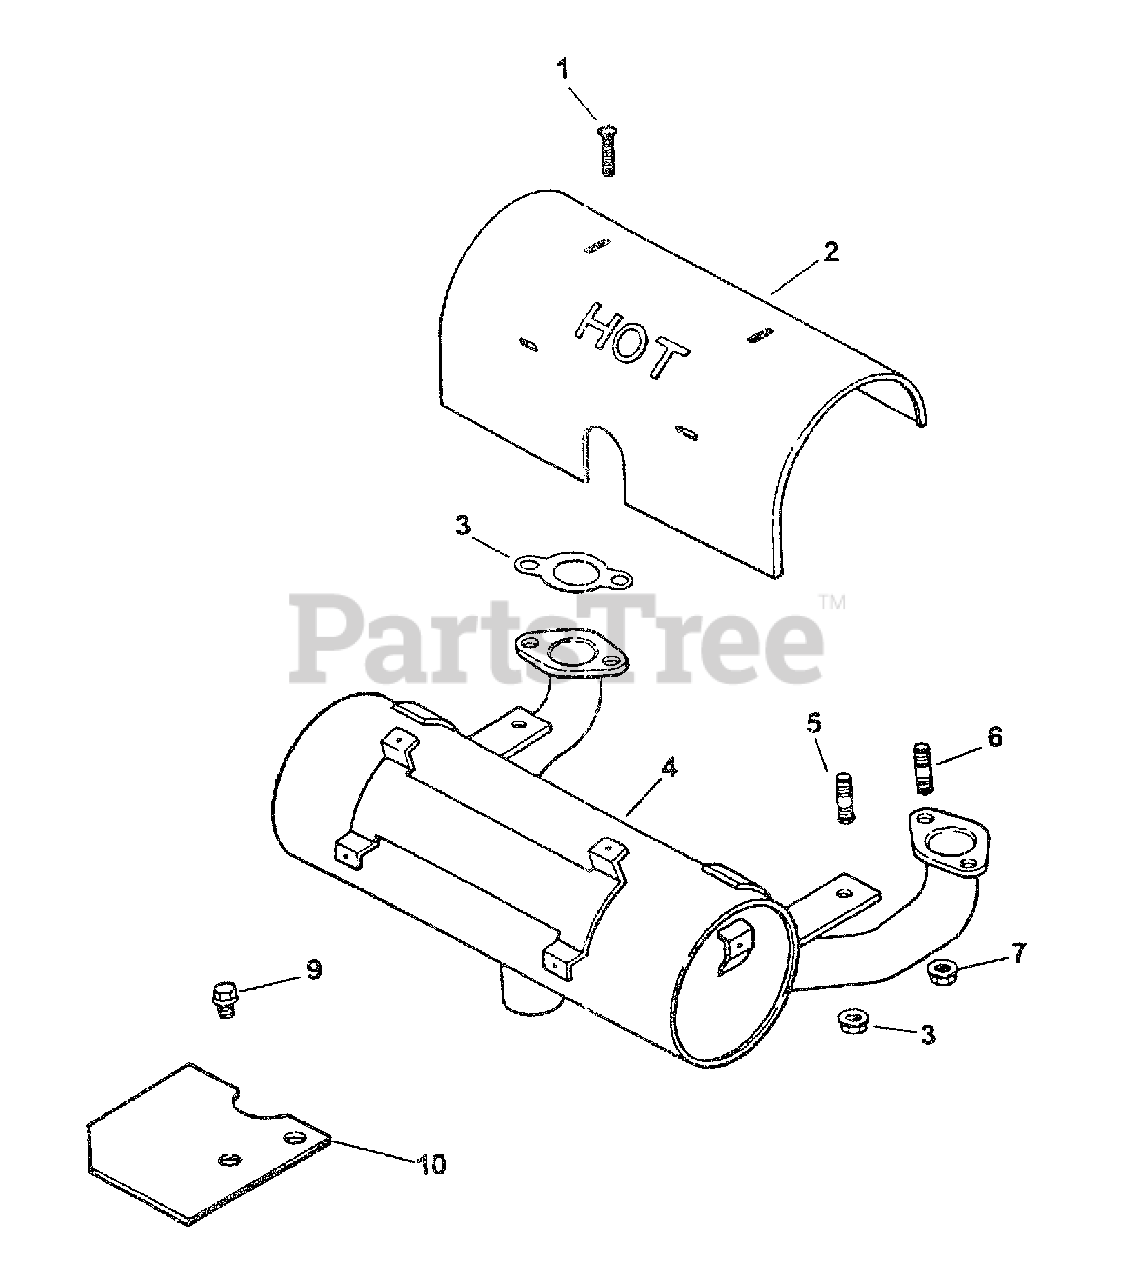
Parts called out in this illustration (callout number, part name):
1	Screw, Sems Drill 8-18 x 9/16"
2	Duct, Heat Shield
3	Gasket, Exhaust
4	Muffler, Center Outlet
6	Stud
7	Nut, Muffler Mounting
9	Screw, Hex Flange
10	Deflector, Heat
